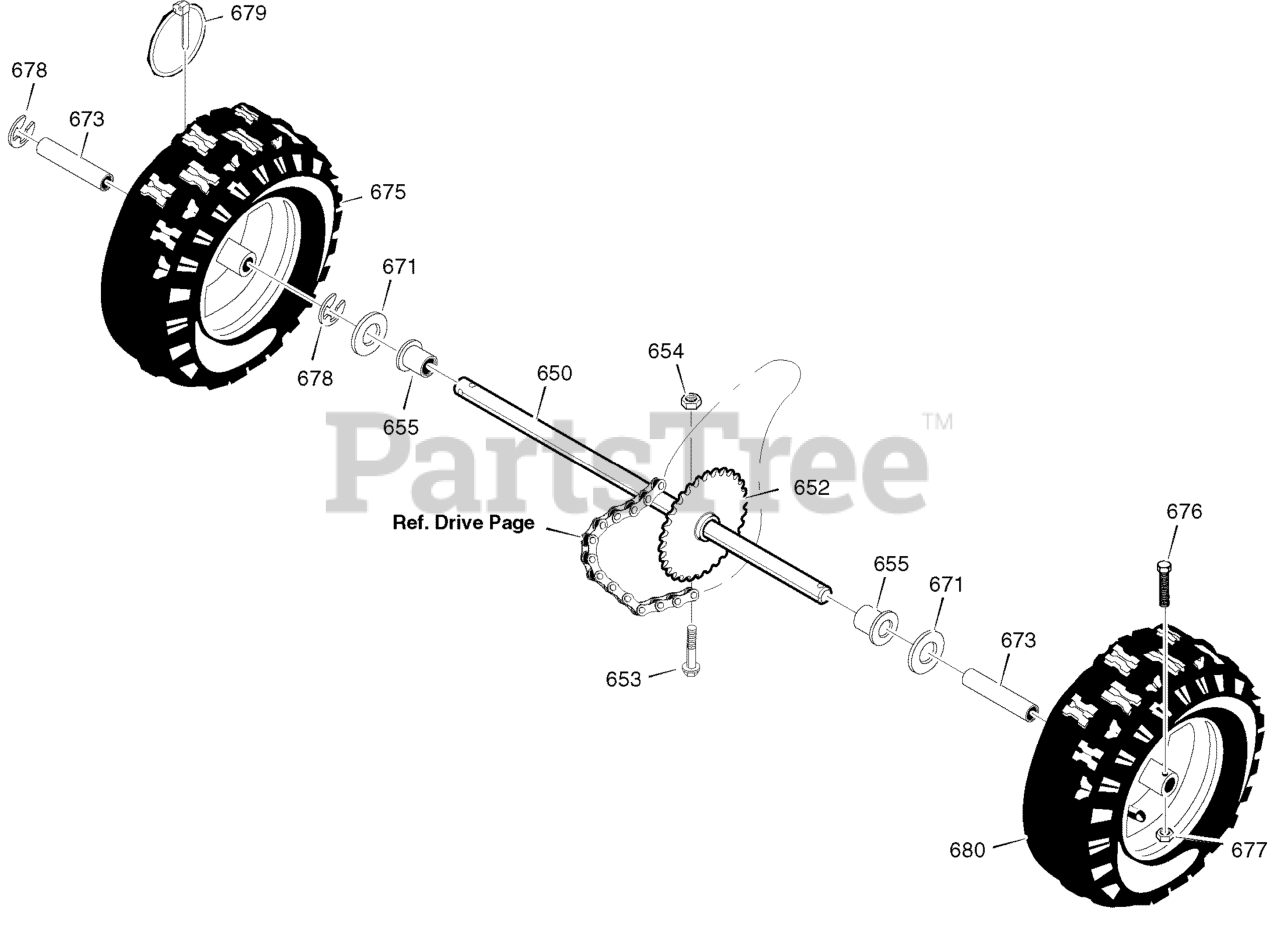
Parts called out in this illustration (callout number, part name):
650	SHAFT, AXLE
652	SPRKT & HUB
653	SCREW, 1/4-20 X 1.75
654	NUT, 1/4-20 HEX NYLOCK
655	BEARING, AXLE
671	FLATWASHER
673	BUSHING, WHEEL
675	TIRE & RIM, RIGHT
676	SCREW, 1/4-20X1.75 HH
677	NUT, 1/4-20 HEX NYLOCK
678	RING, RET
679	PIN, KLIK .25 X 1.38 DIA
680	TIRE & RIM, LEFT
